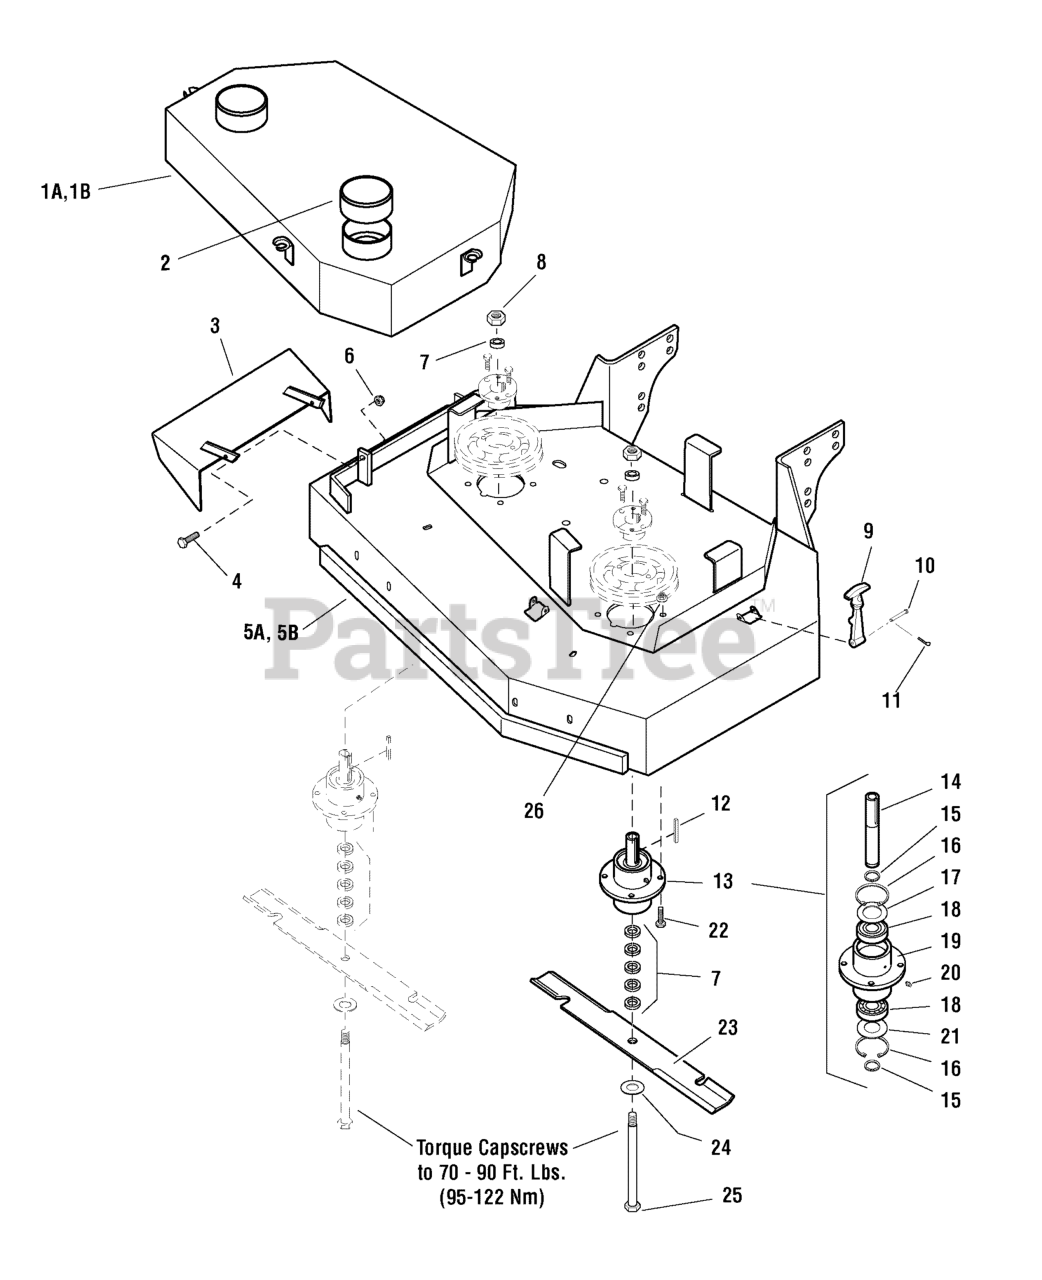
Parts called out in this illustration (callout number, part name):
1A	36" DECK GUARD
1B	36" DECK GUARD
2	VINYL CAP
3	DISCHARGE CHUTE
4	BOLT, 5/16-18 X 1 GD5 YZ
5A	36" MOWER HOUSING
5B	36" MOWER HOUSING ASSEMBLY
6	NUT, 5/16-18 Hex Nylon Lock
7	SPACER, .63 x 1.06 x .23
8	NUT, 5/8-11 Hex
9	RUBBER LATCH
10	CLEVIS PIN
11	COTTER PIN
12	KEY, 1/4 SQ. X 2-1/2
13	SPINDLE ASSEMBLY, Complete
14	SPINDLE SHAFT
15	SNAP RING, External
16	SNAP RING, Internal
17	SPINDLE WASHER, Top
18	BEARING
19	SPINDLE HOUSING
20	GREASE FITTING
21	SPINDLE WASHER, Bottom
22	BOLT, Flange Head, 5/16-18 x 1-1/4
23	MOWER BLADE, 18"
24	WASHER, 5/8" USS
25	BOLT, 5/8-11 x 9-1/2
26	NUT, 5/16-18 Hex Nylon Flange
